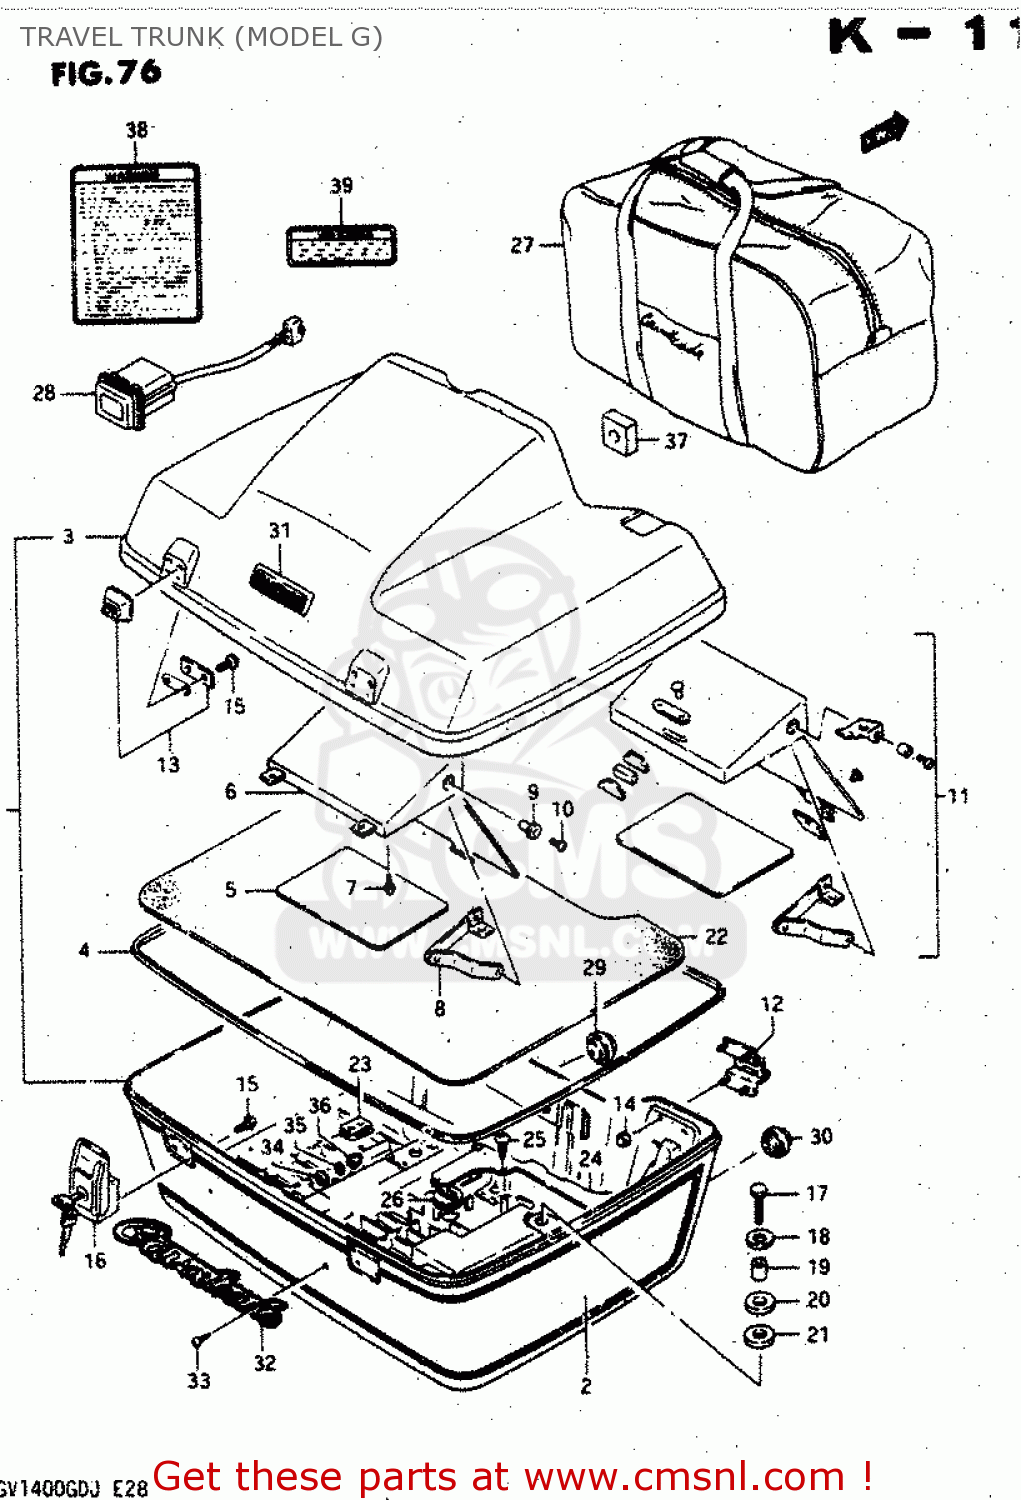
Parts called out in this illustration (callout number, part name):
1	TRUNK ASSEMBLY,TRAVEL
2	TAPE SET,TRAVEL TRUNK
3	LID,TRAVEL TRUNK
4	SEAL,TRAVEL TRUNK LID
5	MIRROR
6	BASE, MIRROR
7	SCREW
8	STOPPER,MIRROR OPEN
9	WASHER
10	SCREW
11	MIRROR,TRAVEL TRUNK
12	HINGE,TRAVEL TRUNK
13	PLATE,TRUNK LID LOCK
14	NUT
15	SCREW
16	LOCK ASSY, SIDE BAG
17	BOLT
18	WASHER (6.5X29X1.6)
19	SPACER(6.3X9.3X16.5)
20	CUSHION
21	CUSHION
22	SEAT,TRAVEL TRUNK BODY
23	GROMMET
24	COVER, AIR HOSE
25	SCREW
26	GROMMET
27	LUGGAGE BAG,TRAVEL TRUNK
28	SWITCH ASSEMBLY,AIR AUXILIARY
29	GROMMET
30	GROMMET
31	EMBLEM,TRAVEL TRUNK,UPPER
32	EMBLEM,TRAVEL TRUNK,LOWER
33	SCREW
34	WASHER
35	WASHER
36	NUT
37	SEAL
38	LABEL (WARNING)
39	LABEL, WARNING
